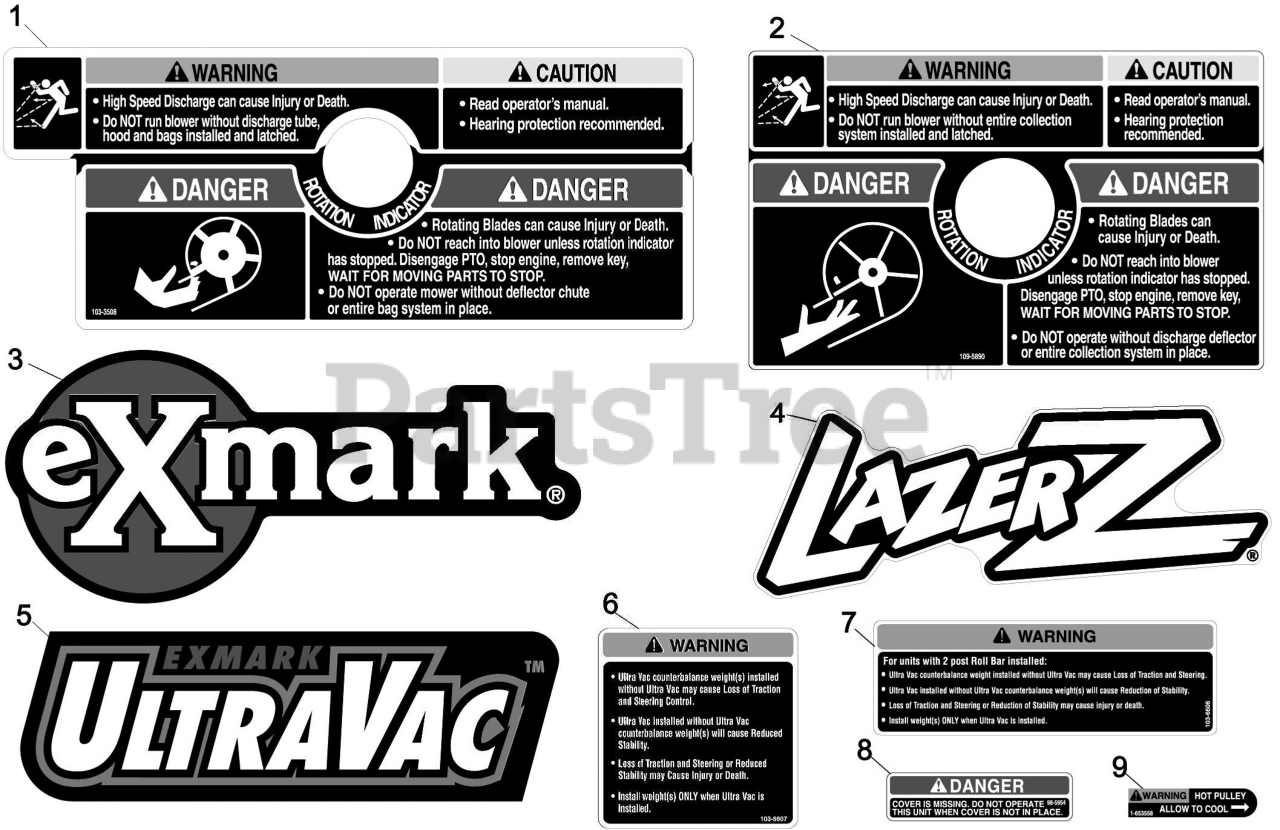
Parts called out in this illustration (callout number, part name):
1	DECAL-WARNING
2	DECAL-WARNING, BLOWER
3	DECAL, EXMARK LOGO
4	DECAL,LAZER MODEL
5	DECAL, ULTRAVAC
6	DECAL,WEIGHT
7	DECAL,WEIGHT
8	DECAL-COVER, MISSING
9	DECAL-WARNING
